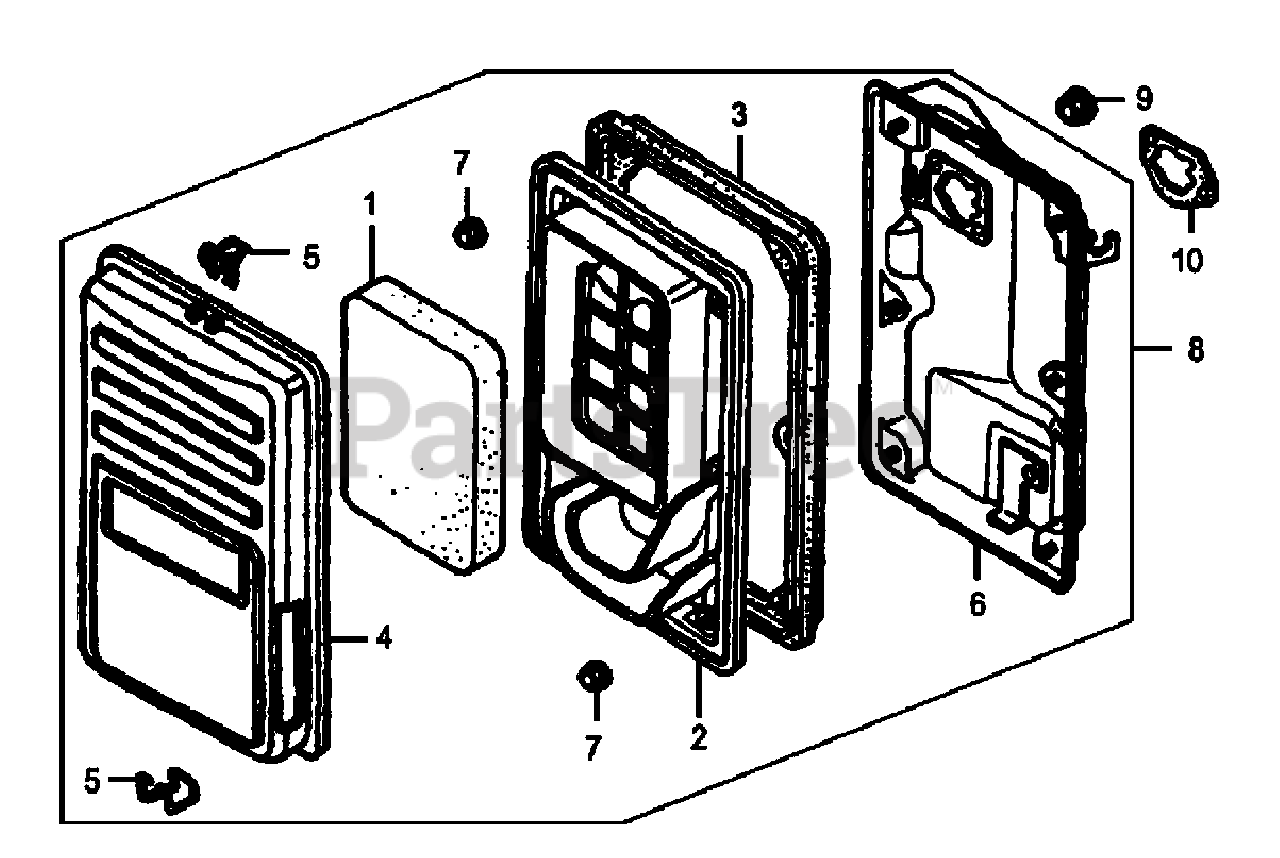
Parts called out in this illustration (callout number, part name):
1	ELEMENT, AIR CLEANER
2	SEPARATOR, AIR CLEANER
3	SEAL, AIR CLEANER
4	COVER, AIR CLEANER
5	CLIP A, AIR CLEANER WIRE
6	CASE COMPLETE, AIR CLEANER
7	NUT,FLANGE
8	CLEANER, AIR
9	NUT, FLANGE
10	PACKING, AIR CLEANER
